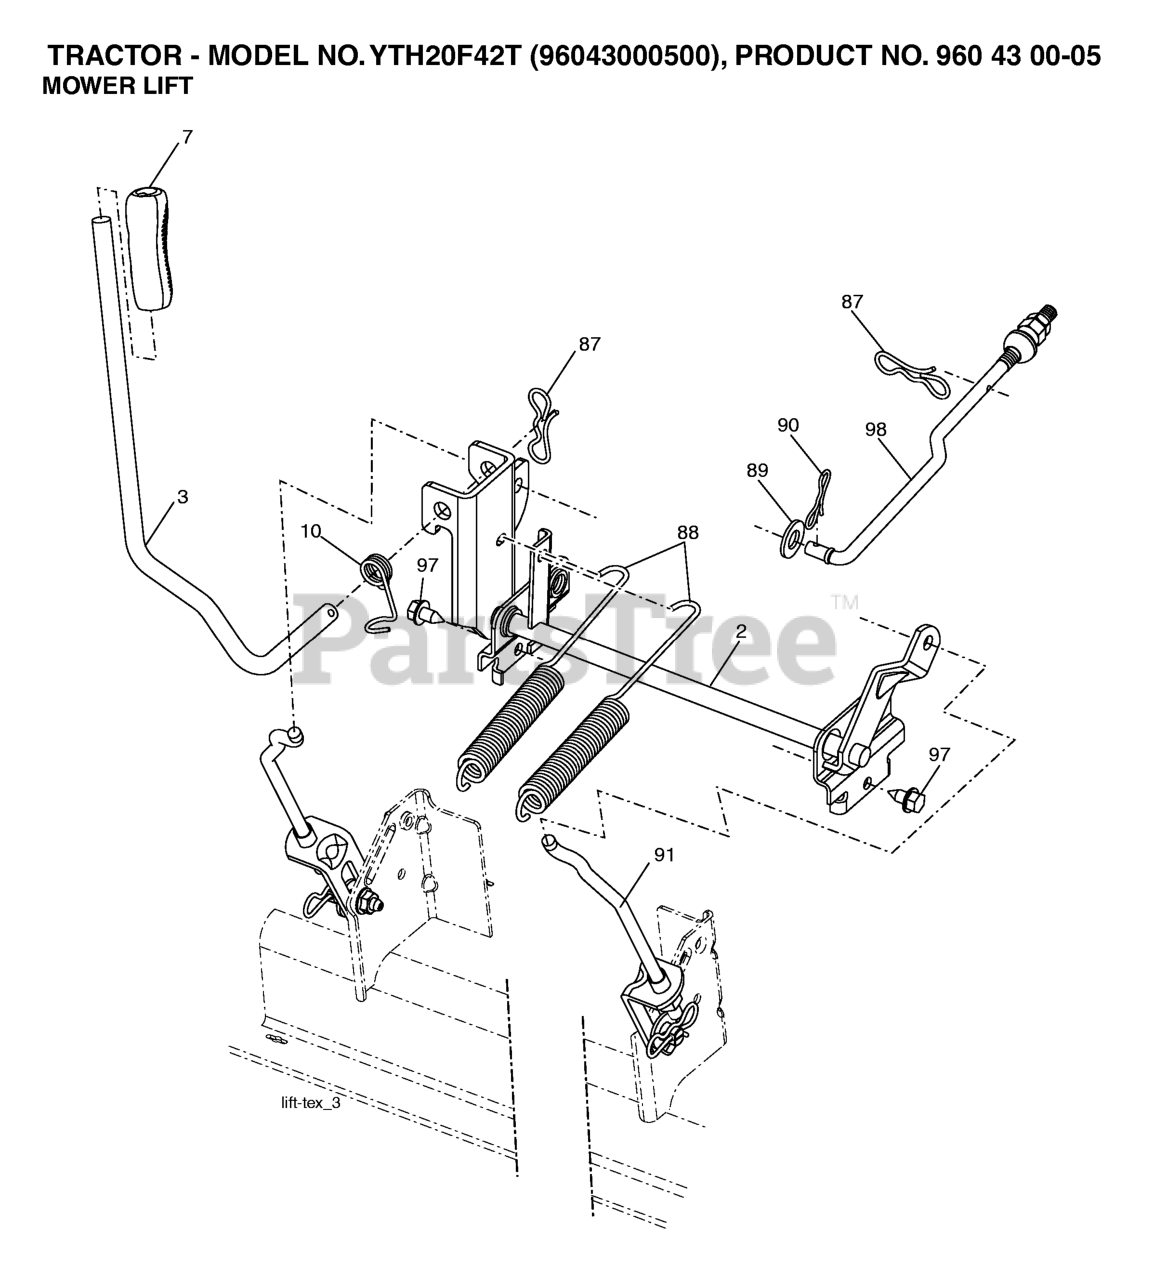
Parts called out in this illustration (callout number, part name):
2	SHAFT.ASM.LIFT.CROSS.H
3	LEVER.LIFT.HANDLE.GT
7	GRIP.LEVER.5625.ID
10	SPRING.TORSION.LIFT.HANDLE
41	NUT, LIFT LINK 7/16-20
87	PIN.COTTER.7/16.BOW TI.
88	SPRING.LIFT.ASSIST.GT2
89	WASHER.CLEAR.ZINC
90	PIN.COTTER.5/16.BOW TI
91	LINK.ASM.LIFT.REAR
97	SCREW 3/8-16X3/4
98	LINK.ASM.SUSP.FRONT.MW
100	NUT **
